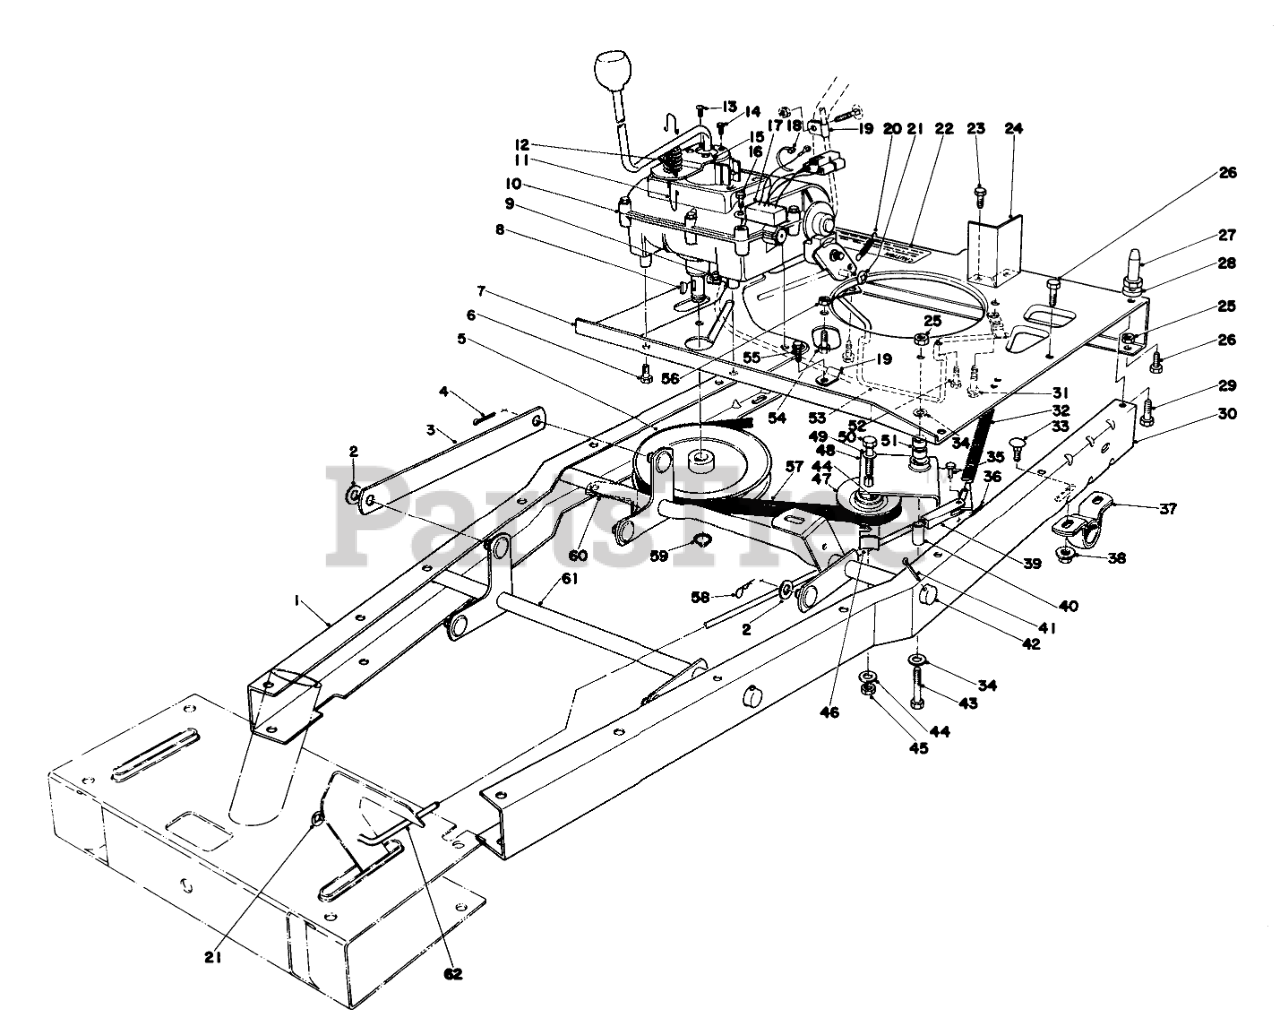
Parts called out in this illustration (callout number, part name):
1	Frame Channel R.H.
2	WASHER-FLAT
3	Linkage-Height Adj.
4	PIN-COTTER
5	PULLEY
6	5/16-18 X 5/8 SEMS SC
7	Engine Plate
8	KEY-WOODRUFF
9	SCREW-HHFTF
10	Transmission
11	Neutral Spring Wire
12	SPRING
15	Neutral Bracket
17	INTERLOCK MODULE-TEC
18	TIE-CABLE
19	CLIP-FUEL LINE
20	SPRING-RETURN, BRAKE
21	PUSH ON SPEED NUT 1/4
22	Decal
23	SCREW-HH
24	Baffle-Carb
25	NUT-LOCK, CONE
26	SCREW-HH
27	PIN-MOUNTING, LOWER
28	SPACER-PIN, MOUNTING
29	SCREW-HH
30	LH FRAME CHANNEL B
31	SCREW-HWHTF
32	Clutch Tension Spring
33	SCREW-CARR
34	WASHER-PLAIN
35	PIN-CLEVIS
36	PIN-COTTER
37	PILLOW BLOCK
38	NUT-HF
40	PIVOT SPACER
41	PIN-COTTER
42	REAR HT ADJ WA B
43	SCREW-HH
44	WASHER-FLAT
45	NUT-LOCK, SIDE
46	RETAINER-BELT
47	PULLEY-IDLER
48	Traction Idler (Incl. Ref. #51)
49	WASHER-FLAT
50	SCREW-HH
51	Bushing
52	Screw-HH
53	Belt Guide
54	SCREW-HH
55	SCREW
56	NUT-HF
57	V-BELT
58	PIN-COTTER
59	RING-SNAP, EXTERNAL
60	TRANS BELT RET B
61	FRONT LIFT WA B
62	Clutch Rod
